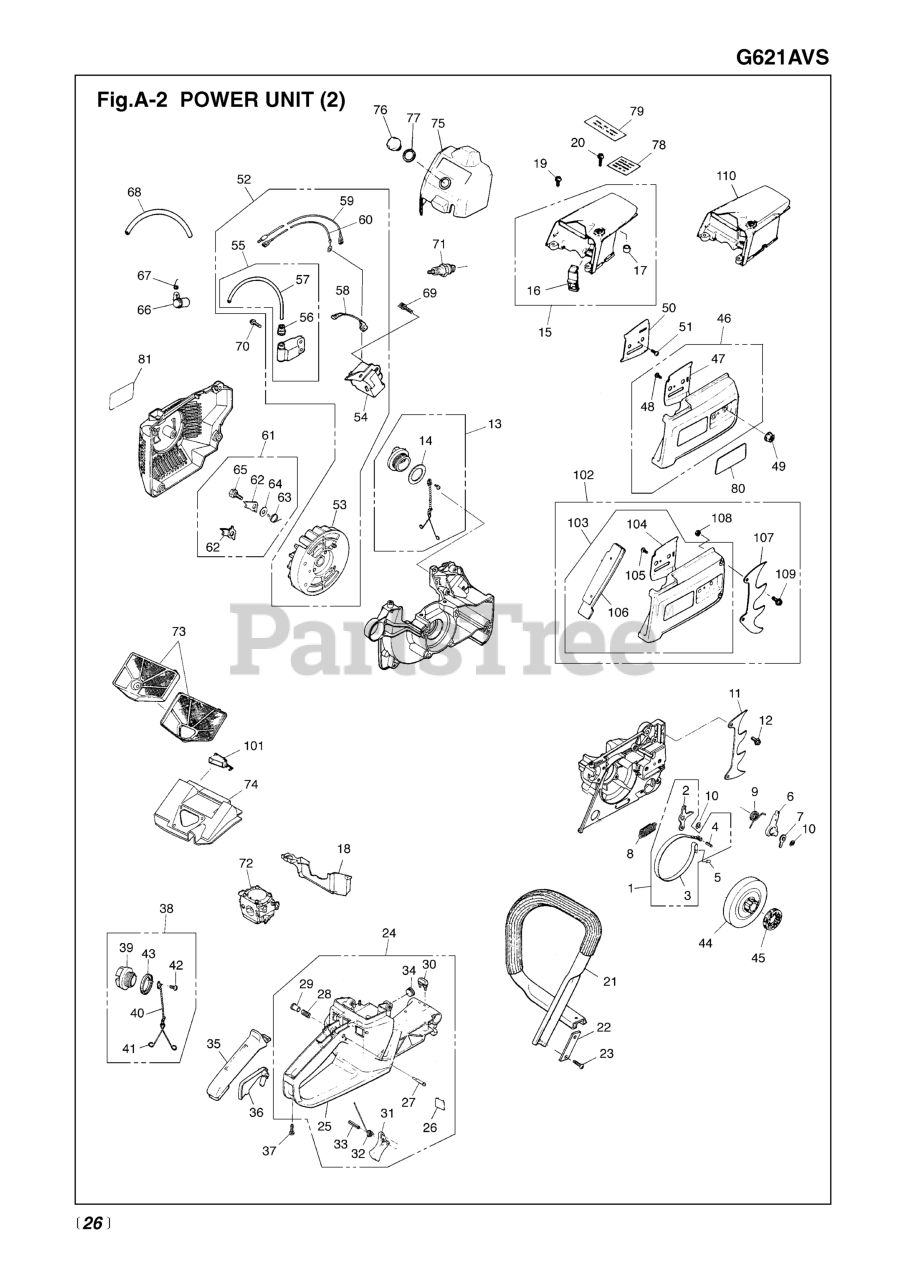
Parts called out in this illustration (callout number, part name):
1	BAND COMP
2	BAND
3	ARM
5	PIN
6	LEVER, BRAKE (RPLS.3356-24210)
8	SPRING COMP
9	SPRING
10	RING, SNAP, M6
11	BUMPER SPIKE
12	SCREW
13	CAP ASSEMBLY
14	GASKET
15	COVER COMP (RPLS -31102)
16	CAP
17	GROMMET (RPLS-31151)
18	SEAL, CYLINDER
19	SCREW,M5 X 14 (RPLS 1400-15510
20	SCREW, M5X20 (RPLS.1400-75510)
21	HANDLE L
22	PLATE (RPLS 2616-32180)
23	SCREW (USE 848-825-1901)
24	R HANDLE ASSY (RPLS -33002)
25	HANDLE (RPLS -33104)
27	STOPPER
29	KNOB
30	DAMPER (REPLACES 3356-33281)
31	LEVER (RPLS 3356-33311)
32	SPRING
34	DAMPER (RPLS -33411)
35	GRIP COVER
37	SCREW
38	TANK CAP ASSY
39	CAP-TANK
42	SCREW, M4 x 10
43	GASKET
44	DRUM, CLUTCH
45	SPROCKET RIM, 3/8, 7-TOOTH
46	COVER, CHAIN (RPLS. -53002)
47	PLATE (OUT)
48	SCREW, M4 x 10
49	NUT
50	PLATE (IN)
51	SCREW, M4 x 10
53	ROTOR (RPLS -71110)
55	COIL, IGNITION
56	CAP
58	CORD
59	CORD
61	ROTOR COMP.
62	RATCHET
63	SPRING (REPLACES -71130)
65	BOLT
66	CAP, PLUG
67	SPRING PLUG (RPLS 3310-71320)
69	BOLT
70	SCREW (REPLACES -30414)
72	CARBURETOR (HDA-212-1)
74	SILENCER
75	COVER (RPLS -83300)
77	GASKET, KNOB
101	CAP, SILENCER
102	DOUBLE SPIKE KIT
103	CHAIN COVER
104	PLATE (OUT)
105	SCREW, M4 x 10
106	PROCTECTOR
107	BUMPER SPIKE
108	NUT (B)
109	SCREW (REPLACES 2616-24320)
110	COVER (G621AVS)
